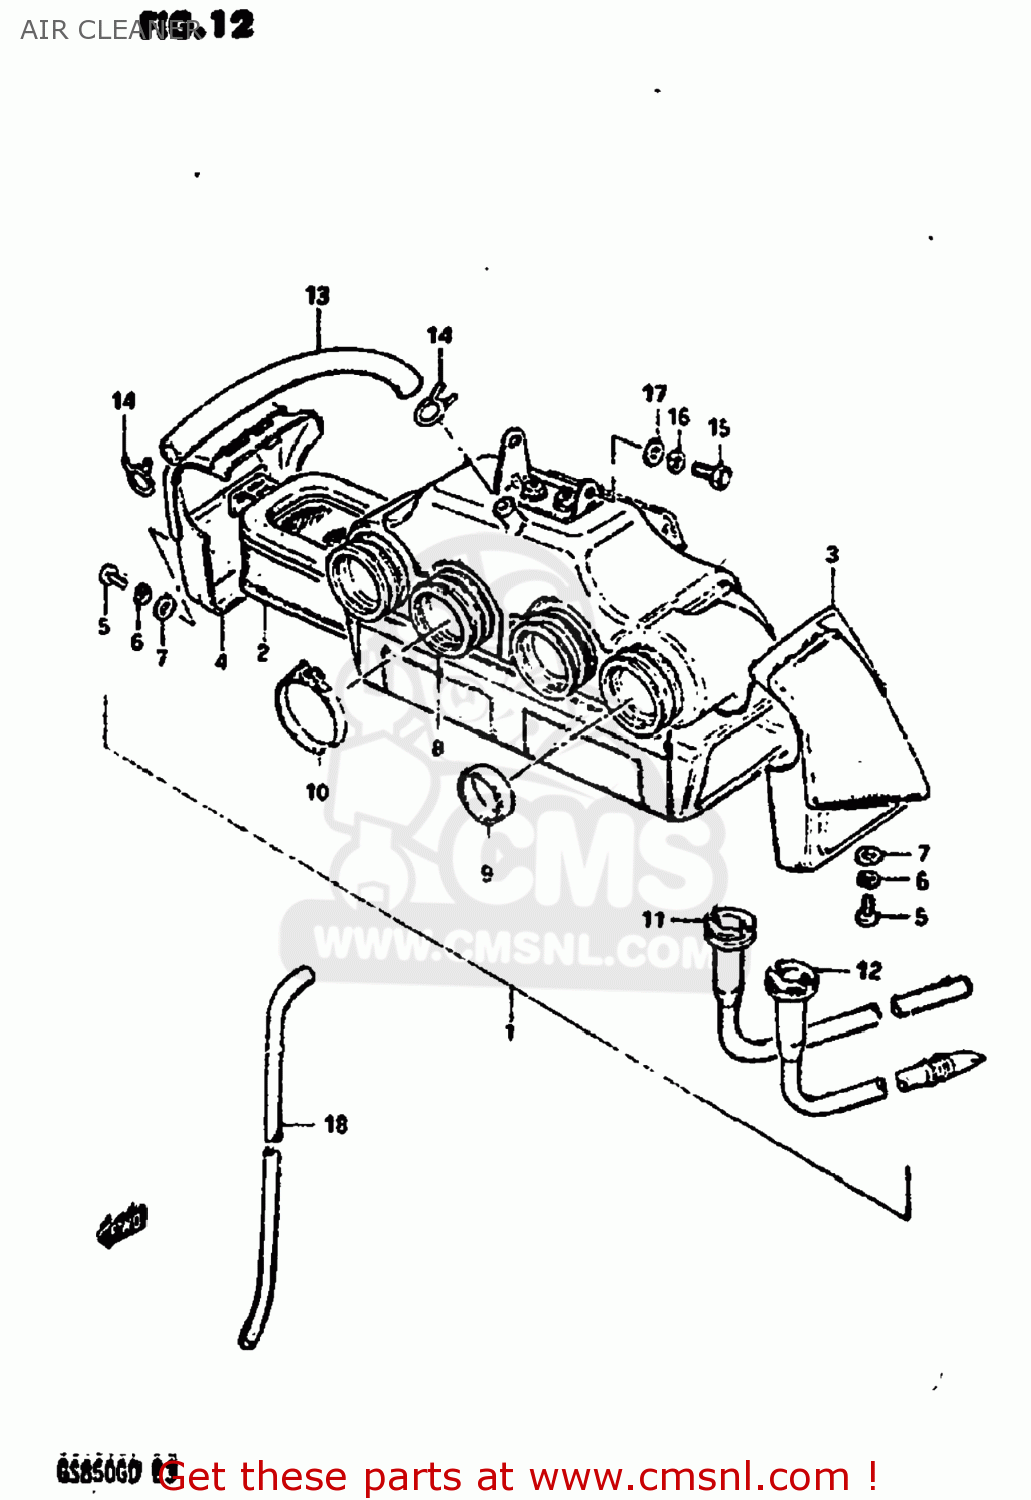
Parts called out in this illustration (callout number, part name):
1	CLEANER ASSEMBLY,AIR
2	FILTER ASSY
3	CAP,AIR CLEANER
4	CAP,AIR CLEANER
5	SCREW
6	LOCK WASHER
7	WASHER
8	TUBE,OUTLET
9	RING
10	CLAMP
11	DRAIN TUBE
12	DRAIN TUBE
13	TUBE,BREATHER
14	CLIP
15	BOLT
16	LOCK WASHER
17	WASHER 6MM
18	HOSE
